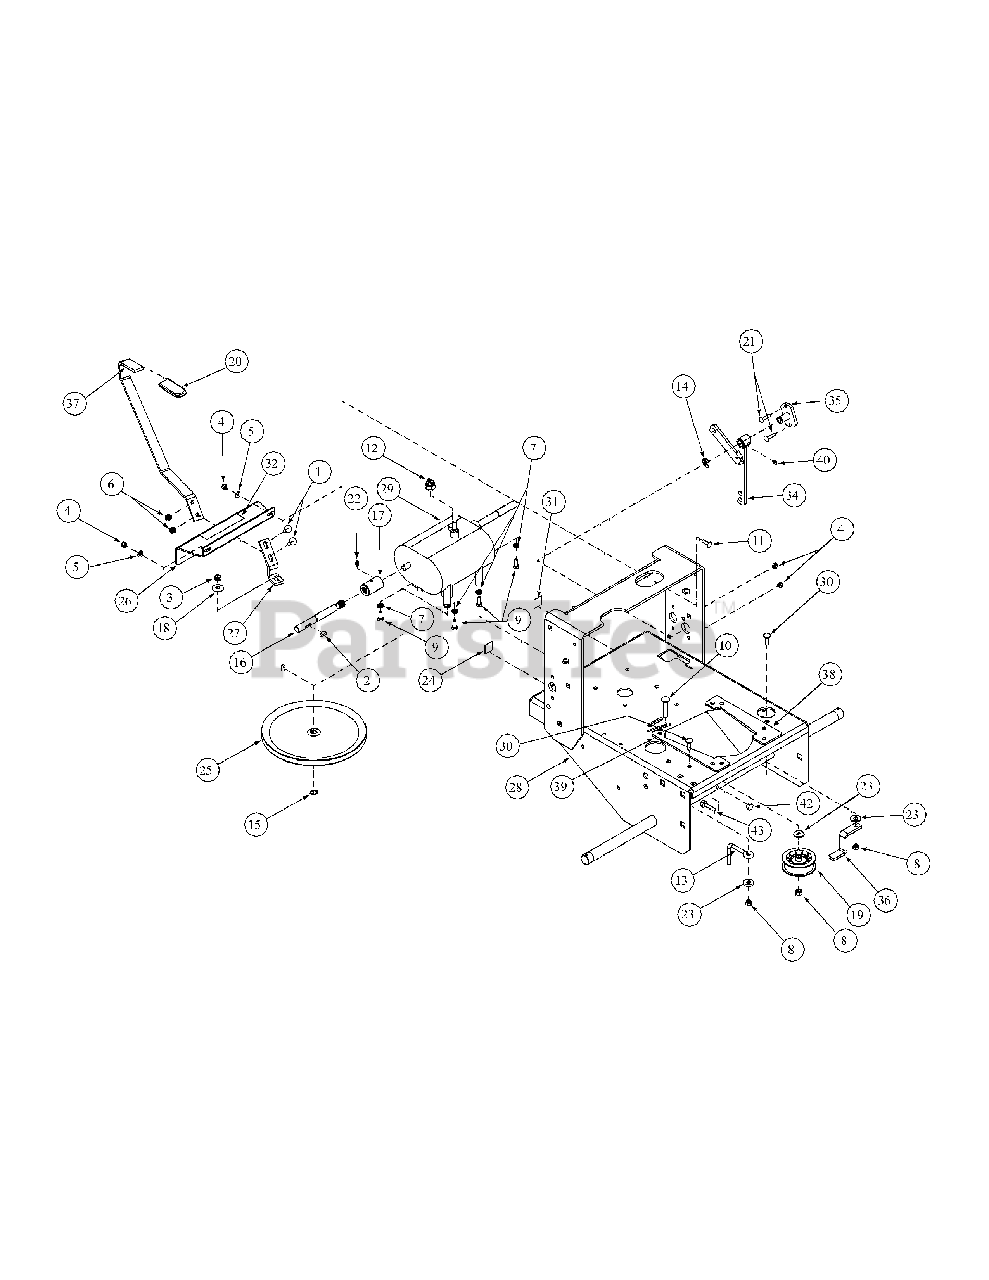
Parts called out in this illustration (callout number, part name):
1	Carriage Bolt, 5/16-18 x 1
2	Woodruff Key, 3/16 x 3/4
3	Jam Nut, Insert Lock, 3/8-24
4	Lock Nut, Nylon Insert, 1/4-20
5	Flat Washer, 1/4 Zinc
6	Nut, 5/16-18 Nylock
7	Lock Washer, 5/16 Zinc
8	Lock Nut, Nylon Insert, 3/8-16
9	Hex Cap Screw, 5/16-18 x 3/4
10	Carriage Bolt, 3/8-16 x2
11	Carriage Bolt, 1/4-20 x .750
12	Switch, WB Transmission
13	Drive Belt Guide
14	E-Ring, 5/8
15	External Retainer Ring
16	Jackshaft w/ Heavy Spline
17	Coupling w/Heavy Spline
18	Bell Washer, .39 ID x 1.13 OD x .062
19	Flat Idler Pulley w/Adapter
20	Grip, .250 x 1 x 3-1/2, Yellow
21	Carriage Bolt, 1/4-20 x 1.00
22	Grease Fitting, 1/4-28 x 3/16
23	Idler Washer
24	Decal "Made In America
25	Transmission Pulley
26	Shift Plate
27	Shift Arm
28	Engine Deck Assembly
29	Transmission, 5 Speed
30	Carriage Bolt, 3/8 -16 x 1.25
31	Label, Warning, Open Belt Drive
32	Label, Mower Instruction
34	Clutch, Bellecrank Weldment
35	Bellecrank Pivot, Weldment
36	Engine Belt Guide
37	Shift Handle
38	Engine Spacer, LH
39	Engine Spacer, RH
40	Grease Fitting, 1/4-28 x 3/16
42	Hex Lock Nut, 1/4-20
43	Hex Cap Screw, 1/4-20 x 2
